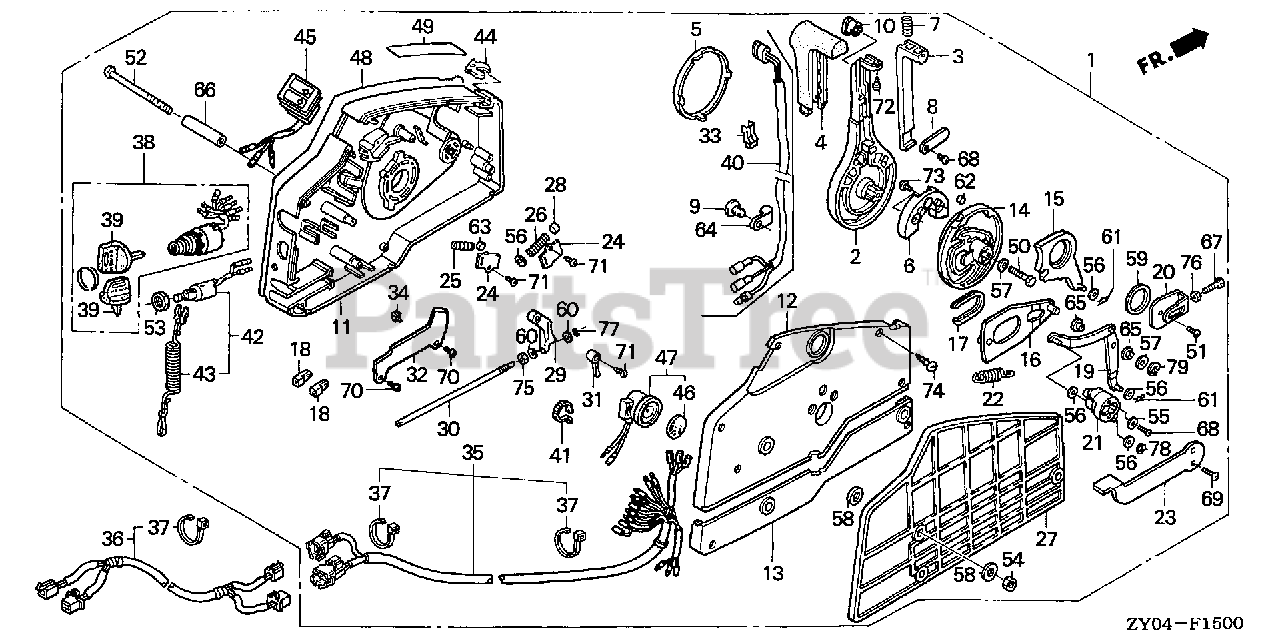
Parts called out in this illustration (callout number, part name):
1	S/R SW 2 LIGH POW TL
1	BOX ASSY., REMOTE CONTROL (PT)
1	BOX ASSY., REMOTE CONTROL (HI-LEX)(PT)
2	HANDLE, REMOTE CONTROL
3	LEVER, HANDLE LOCK
4	GRIP, REMOTE CONTROL HANDLE
5	CAP, HANDLE
6	BLOCK, NEUTRAL LOCK
7	SPRING, REMOTE CONTROL HANDLE
8	PLATE, LEVER SETTING
9	CLAMP, HARNESS
11	HOUSING, REMOTE CONTROL BOX (A)
12	HOUSING, REMOTE CONTROL BOX (B)
13	HOUSING, REMOTE CONTROL BOX (C)
14	WHEEL, CONTROL
15	ARM, SHIFT LINK
16	PLATE, SLIDING
17	COLLAR, SLIDING PLATE
18	PIVOT, SHIFT
19	ARM, LINK JOINT
20	BRACKET, LINK JOINT
21	WHEEL, ACCELERATOR
22	SPRING, ACCELERATOR WHEEL
23	LEVER, IDLE
24	PLATE, SPRING SETTING
25	SPRING, SHIFT CLICK
26	SPRING, CHOKE RETURN
27	SPACER, REMOTE CONTROL BOX
28	SPACER, CLICK SPRING
29	BLOCK, THROTTLE FRICTION
30	BOLT, FRICTION
31	SPACER, NEUTRAL SWITCH
32	CLAMP, POWER TILT CORD
33	PIPE, HARNESS GUIDE
34	SPACER, CABLE CLAMP
35	CABLE ASSY. B, REMOTE CONTROL (4P+6P)
36	CABLE ASSY., REMOTE CONTROL EXTENSION (4P+6P)
37	TIE, CABLE (2.4X92) (NATURAL)
38	SWITCH ASSY., COMBINATION
39	KEY ASSY., COMBINATION SWITCH (35100-ZV5-003 ONLY)
40	SWITCH ASSY., POWER TRIM-TILT
41	BAND (BLACK 3.5X140)
42	SWITCH ASSY., EMERGENCY STOP
43	WIRE, EMERGENCY
44	CLIP, EMERGENCY LOCK
45	LAMP ASSY., INDICATOR
46	PLATE, TURN SIGNAL BUZZER
47	BUZZER, WARNING
48	PLATE, REMOTE CONTROL (CAUTION PICT=SILVER)
49	MARK, FAST IDLE
50	BOLT, HEX. (8X35)
51	SCREW, PAN (6X10)
52	SCREW (6X95)
53	NUT, HEX. (16MM)
54	NUT, HEX. (6MM)
55	WASHER, PLAIN (5MM)
56	WASHER, PLAIN (6MM)
57	WASHER, PLAIN (8MM)
58	WASHER (6MM)
59	WASHER (28MM)
60	WASHER, PLAIN (4MM)
61	PIN, LOCK (6MM)
63	ROLLER, CLICK
64	CLIP, WIRE HARNESS (6.3MM)
65	COLLAR, LINK JOINT
66	COLLAR, DISTANCE (6X10X43.5)
67	BOLT, HEX. (5X16)
68	SCREW, PAN (5X10)
69	SCREW, OVAL (5X12)
70	SCREW, TAPPING (5X8)
71	SCREW, TAPPING (5X10)
72	SCREW, TAPPING (5X12)
73	SCREW, TAPPING (6X16)
74	SCREW, TAPPING (5X25)
75	NUT, HEX. (6MM)
76	NUT, HEX. (5MM)
77	E-RING (3MM)
78	E-RING (4MM)
79	E-RING (7MM)
